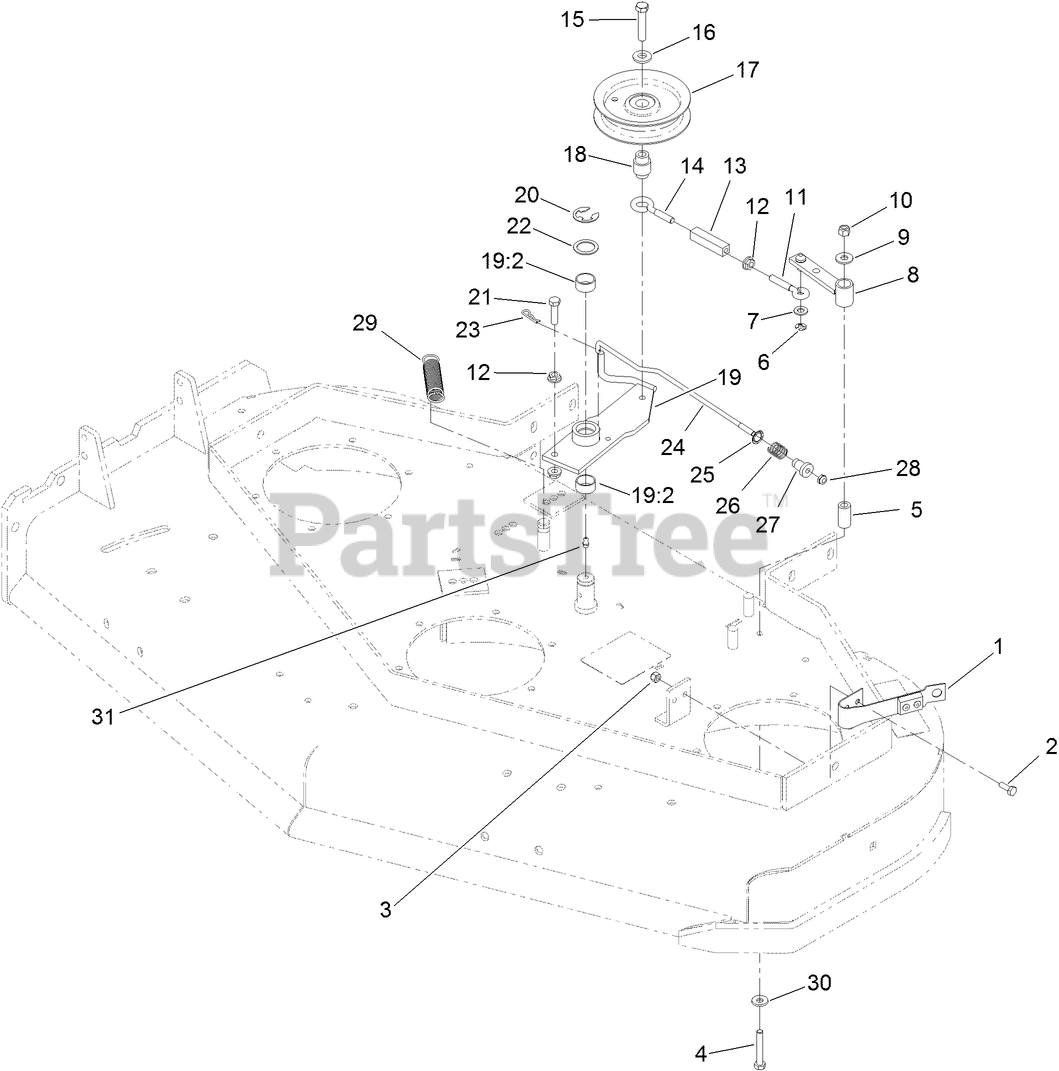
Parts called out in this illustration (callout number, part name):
1	PAD AND SPRING ASM
2	SCREW-HH
3	NUT-LOCK, NI
4	SCREW-HH
5	TUBE-PIVOT
6	RING-RETAINING, EXT
7	WASHER-PLAIN
8	ARM-ASSIST, 32/36
9	WASHER-FLAT
10	NUT-LOCK, NI
11	EYEBOLT-THREAD, RH
12	NUT-HF
13	BODY-TURNBUCKLE
14	EYEBOLT-THREAD, LH
15	SCREW-HH
16	WASHER-BELLEVILLE
17	PULLEY-IDLER, FLAT
18	BUSHING-ENGAGEMENT
19	IDLER ARM ASM
19:2	SLEEVE-BEARING
20	RING-RETAINING, EXT
21	SCREW-HH, SPECIAL
22	WASHER-SPINDLE
23	PIN-COTTER
24	ROD-BRAKE
25	RING-PUSH ON
26	SPRING-COMPRESSION
27	SPACER-FLANGED
28	NUT-LOCK, NI
29	SPRING-EXTENSION
30	WASHER-SPRING
31	FITTING-GREASE, 90 DEG
